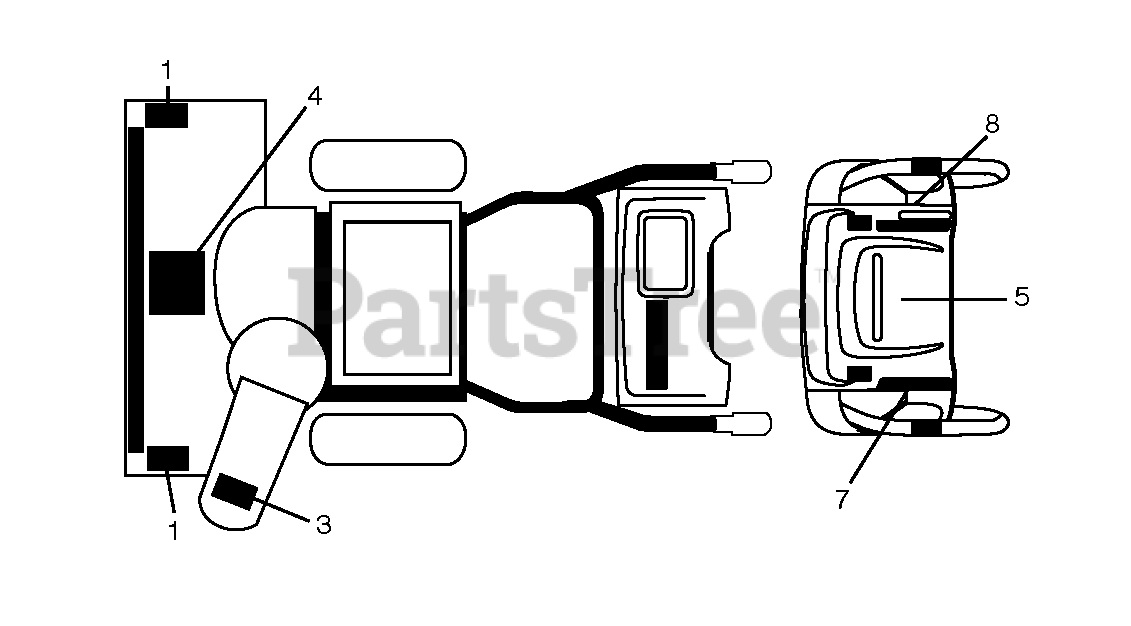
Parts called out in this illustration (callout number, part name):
1	DECAL.SNOWTHR.AUGER
3	DECAL.SNOWTHR.CHUTE.SAFETY
4	DECAL.SNOWTR.READ.OWN.MAN.E/F
5	DECAL.CONSOLE.SNOW.INST.ENG/FR
7	DECAL.CONS.LT.SPD/LEV/PWRST.
8	DECAL.CONS.RT.SPD/LEV/PWRST.
